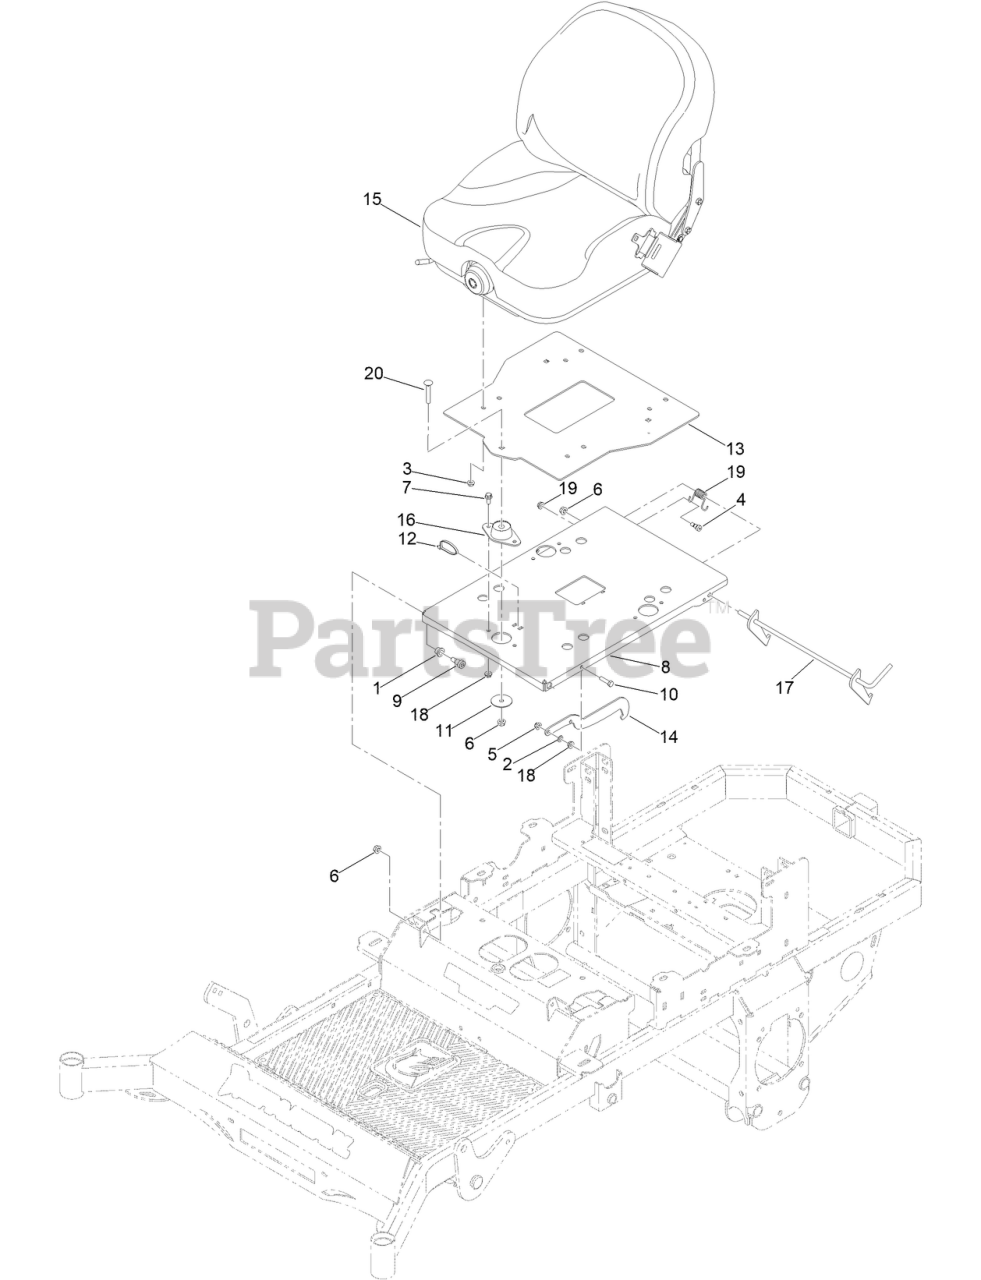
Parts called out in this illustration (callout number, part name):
1	1/2IN ID X 5/8IN OD X 1/2IN FLANGE BUSH
2	.312IDX.625ODX.062 THK THRUST BRG OI BRZ
3	5/16-18 NYLON INSERT FLANGE L/NUT ZC
4	SCREW-HSH
5	NUT-HF, NI
7	SCREW-HHF
8	ASM, PLATE-SEAT BASE UPGRADE W/ DECALS
8	2019 UPGRADE SEAT BASE PLATE PAINT
9	1/2 X 1/2 SOCKET SHOULDER BOLT ZC YELLOW
10	SCREW-HH
11	3/8 X 2IN OD FENDER WASHER YZ
12	6IN (40 LB) CABLE TIE NYLON UV
13	2019 UPGRADE SEAT PLATE PAINT
14	MWR SEAT LATCH HOOK PAINT
15	2019 FULL SUSP SEAT
16	FLOATING SEAT DAMPER-STIFFER
17	MWR SEAT LATCH RELEASE ASSY ABC
19	MWR SEAT LATCH SPRING
20	SCREW-CARR
